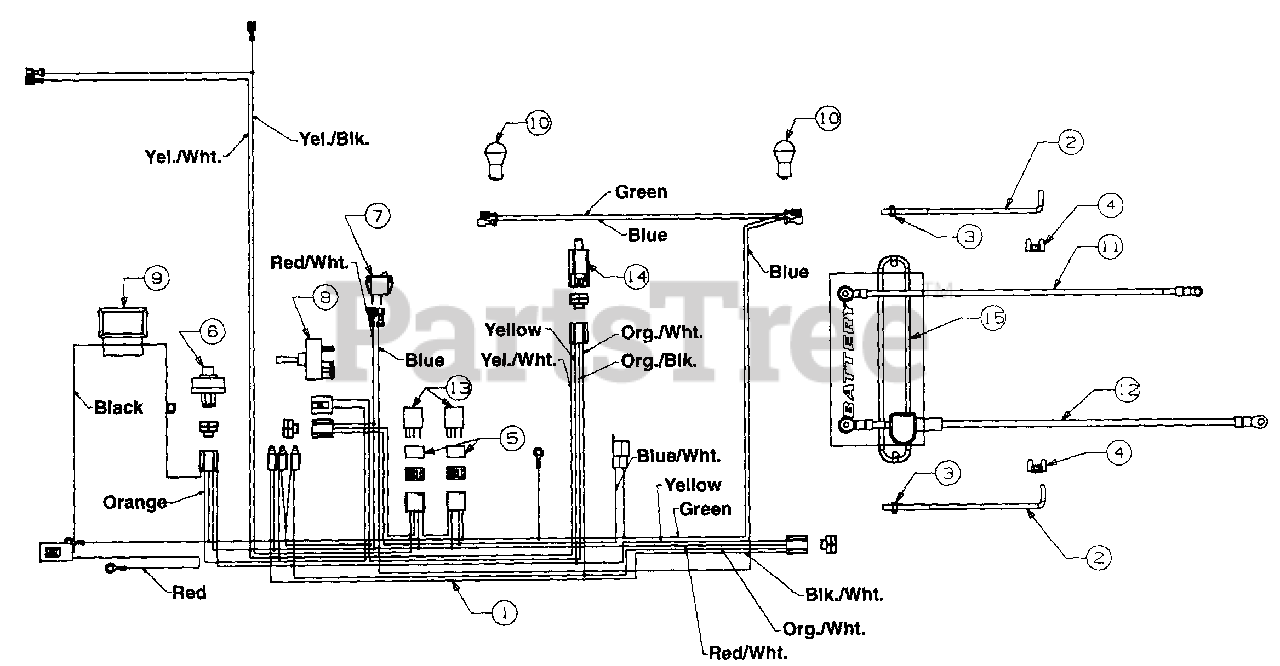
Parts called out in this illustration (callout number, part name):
1	Wire Harness
2	Battery Hold Down Rod
3	Hex L-Nut 1/4-20 Thd.
4	Wing Nut 1/4-20 Thd.
5	Gasket
6	Ignition Switch
7	Light Switch
8	Switch (PTO)
9	Ammeter
10	Bulb (Headlight)
11	Wire 17" Lg.
12	Wire w/Boot 20" Lg.
13	Relay
14	Safety Switch (Clutch)
15	Battery Cover
